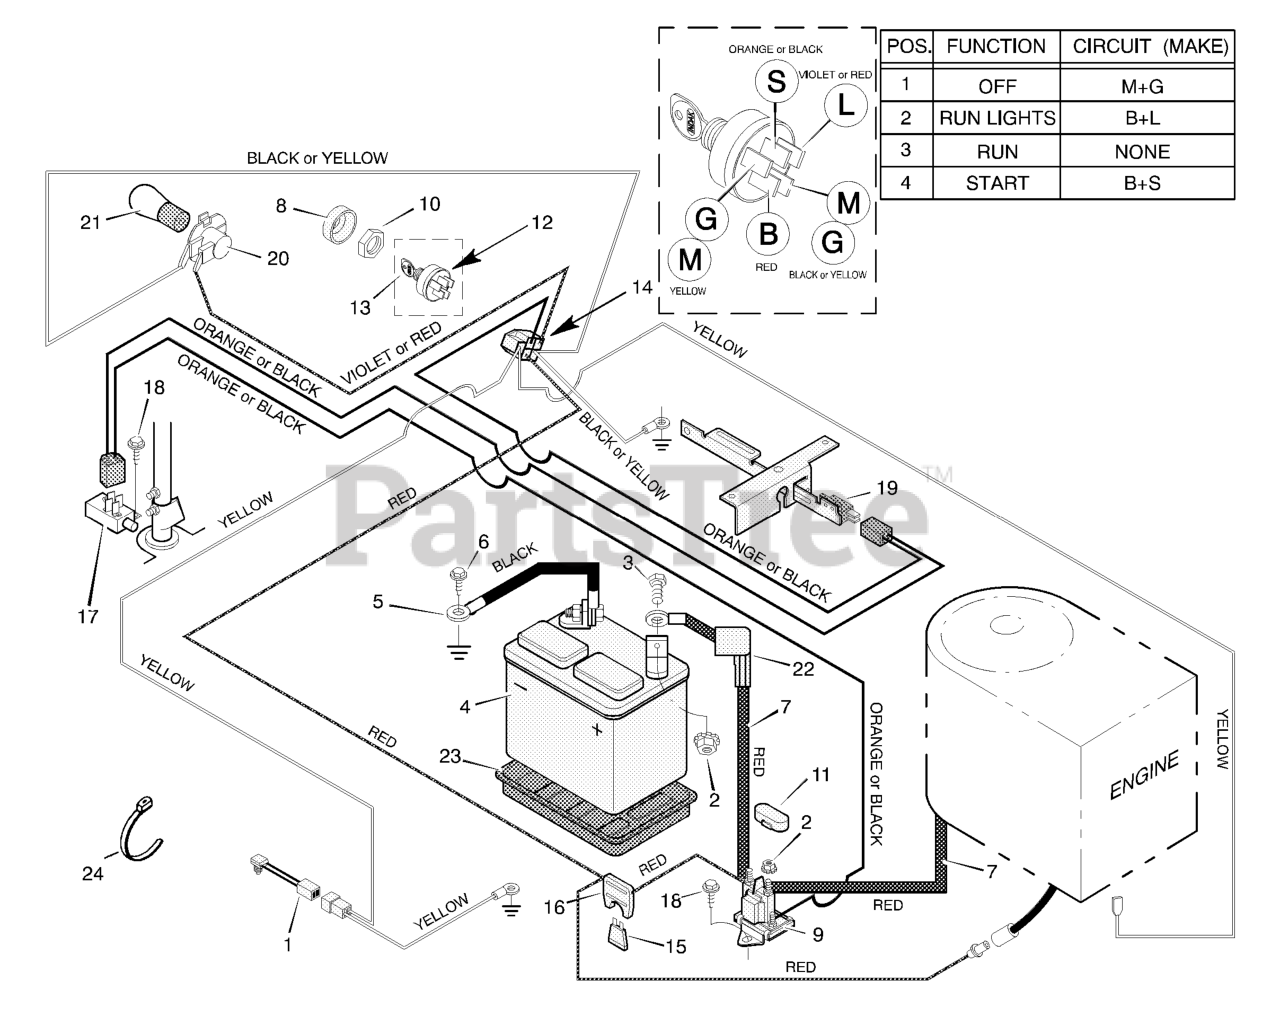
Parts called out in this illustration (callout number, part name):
1	Switch, Seat Sensor
2	Locknut
4	Battery
5	Cable, Battery Ground
7	Cable, Red Battery
8	Cap, Ignition
9	Solenoid
10	Nut, Hex
12	Switch, Ignition
13	Key, Ignition
14	Harness, Chassis Wire
16	Holder, Fuse
17	Switch, Limit
19	Switch, Limit
20	Socket, Light
21	Bulb, Light
22	Cover, Terminal
23	Tray, Battery
